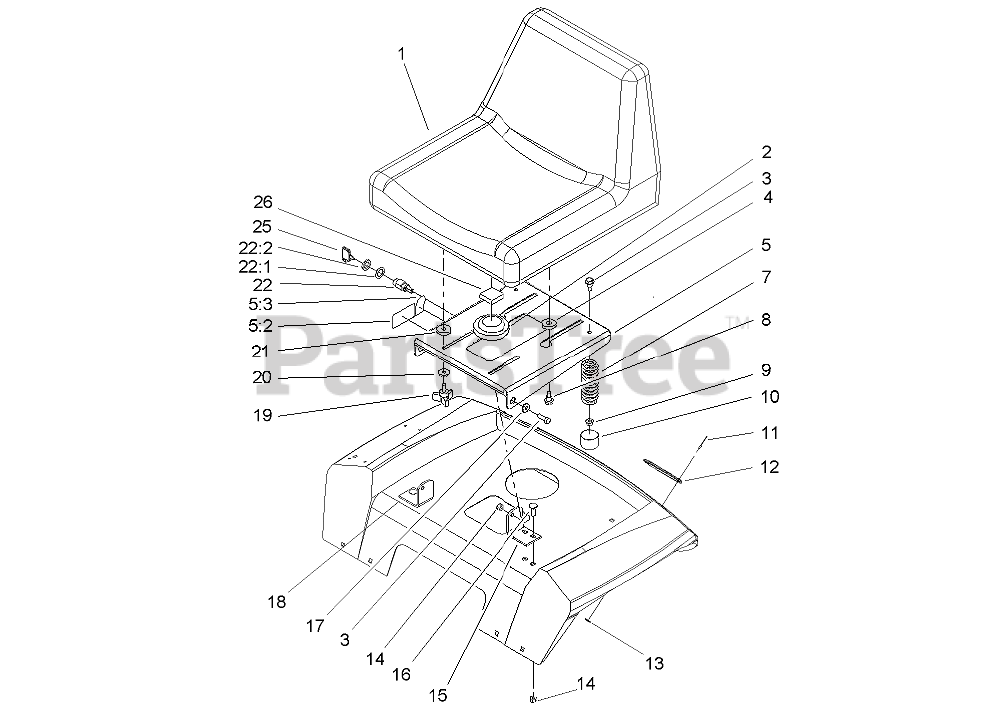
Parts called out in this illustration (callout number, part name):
1	SEAT
2	SWITCH-SEAT
3	SCREW-HH
4	SPACER-NYLON
5	SUPPORT SEAT ASM
5:2	DECAL-DANGER
5:3	DECAL
7	SPRING-COMPRESSION
8	BOLT-SHOULDER
9	NUT-HF
10	CAP-PROTECTOR
11	RIVET-BLIND
12	REFLECTOR-STICK ON
13	WASHER-PLAIN
14	NUT-LOCK, NI
15	BRACKET-PIVOT, RH
16	SCREW-CARR
17	BUSHING
18	BRACKET-PIVOT, LH
20	WASHER
21	SPACER-NYLON
22	STARTER SWITCH ASM
22:1	WASHER-TOOTH, INTERNAL
22:2	NUT-HH
25	KEY-IGNITION
26	FOAM-SWITCH, SEAT
